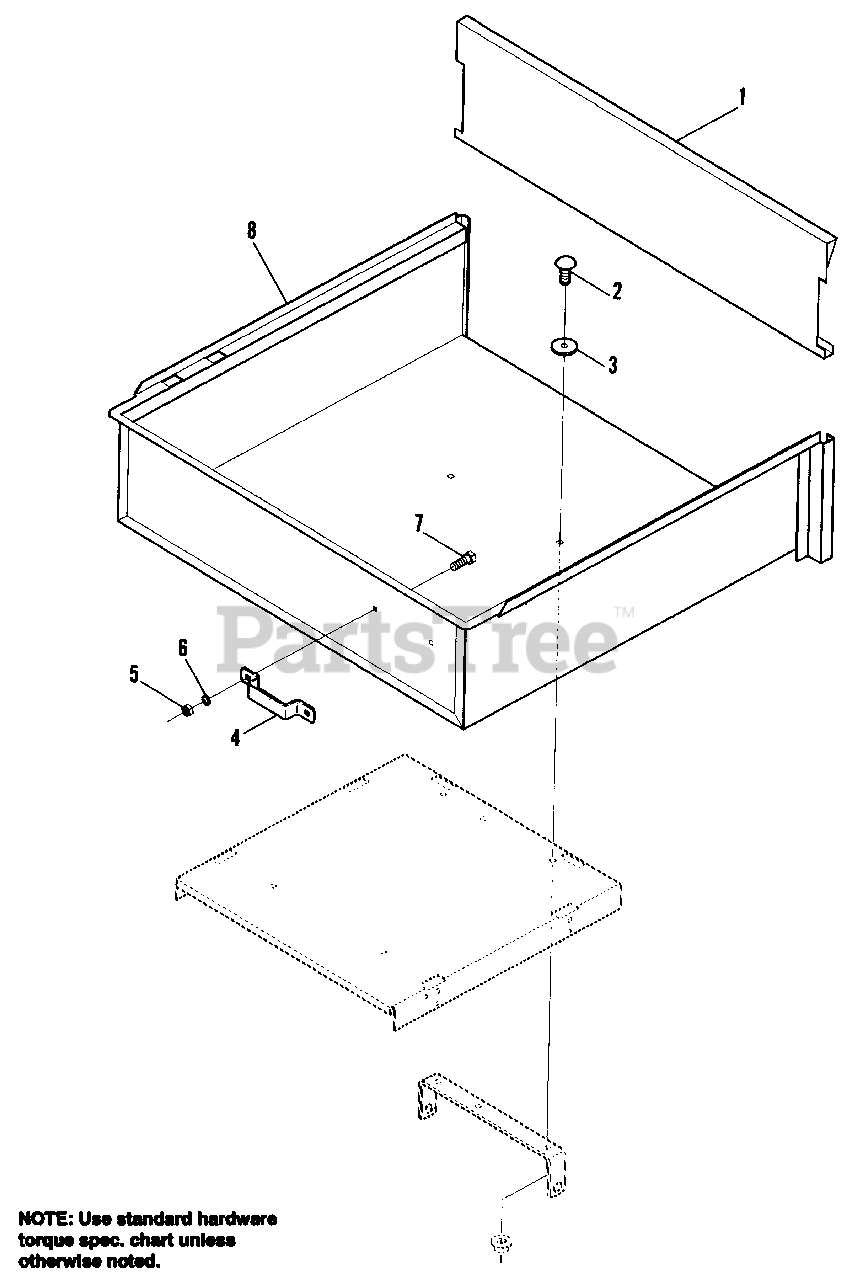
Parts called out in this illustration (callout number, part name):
1	TAILGATE (1691808)
1	TAILGATE (1692100)
2	WASHER, Plain, 7/16 x 1-1/4
3	CARRIAGE BOLT, 5/16-18 x 7/8
4	HANDLE, Lift
5	NUT, Hex, 1/4-20
6	LOCKWASHER, Spring, 1/4
7	CAPSCREW, 1/4-20 x 1/2
8	BOX (1691808)
8	BOX (1692100)
